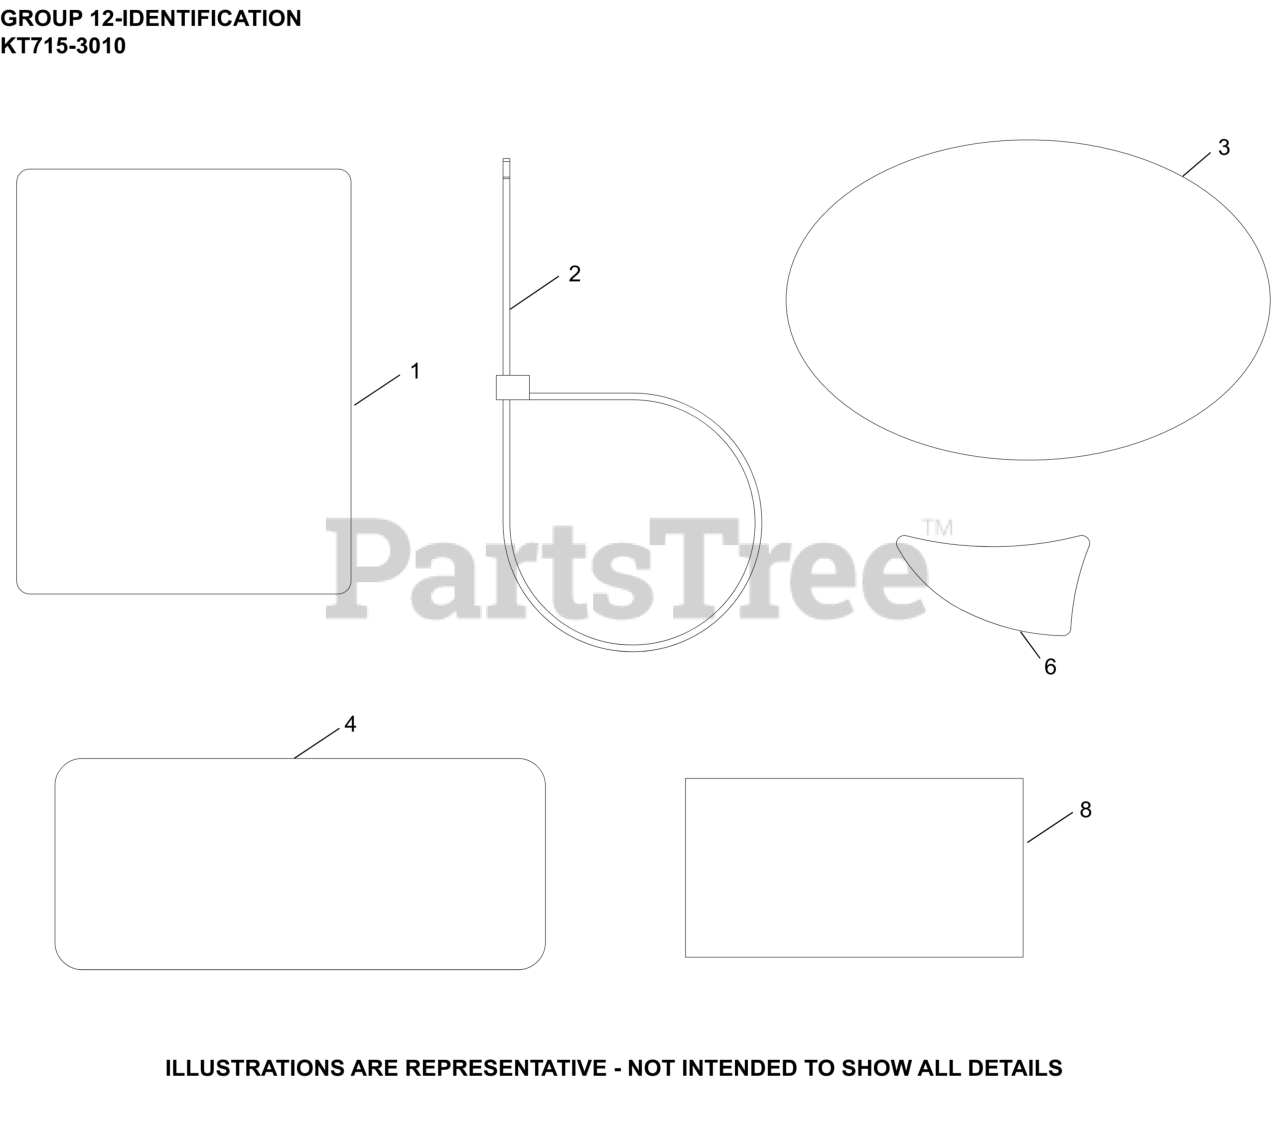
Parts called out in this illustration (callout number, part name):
1	LABEL, CLEAR LAMINATION
3	LABEL, 7000 SERIES (20HP, PRO)
4	LABEL, CANADIAN COMPLIANCE
6	LABEL, HI PERFORMANCE AIR FILTRATION
8	DECAL, USA
